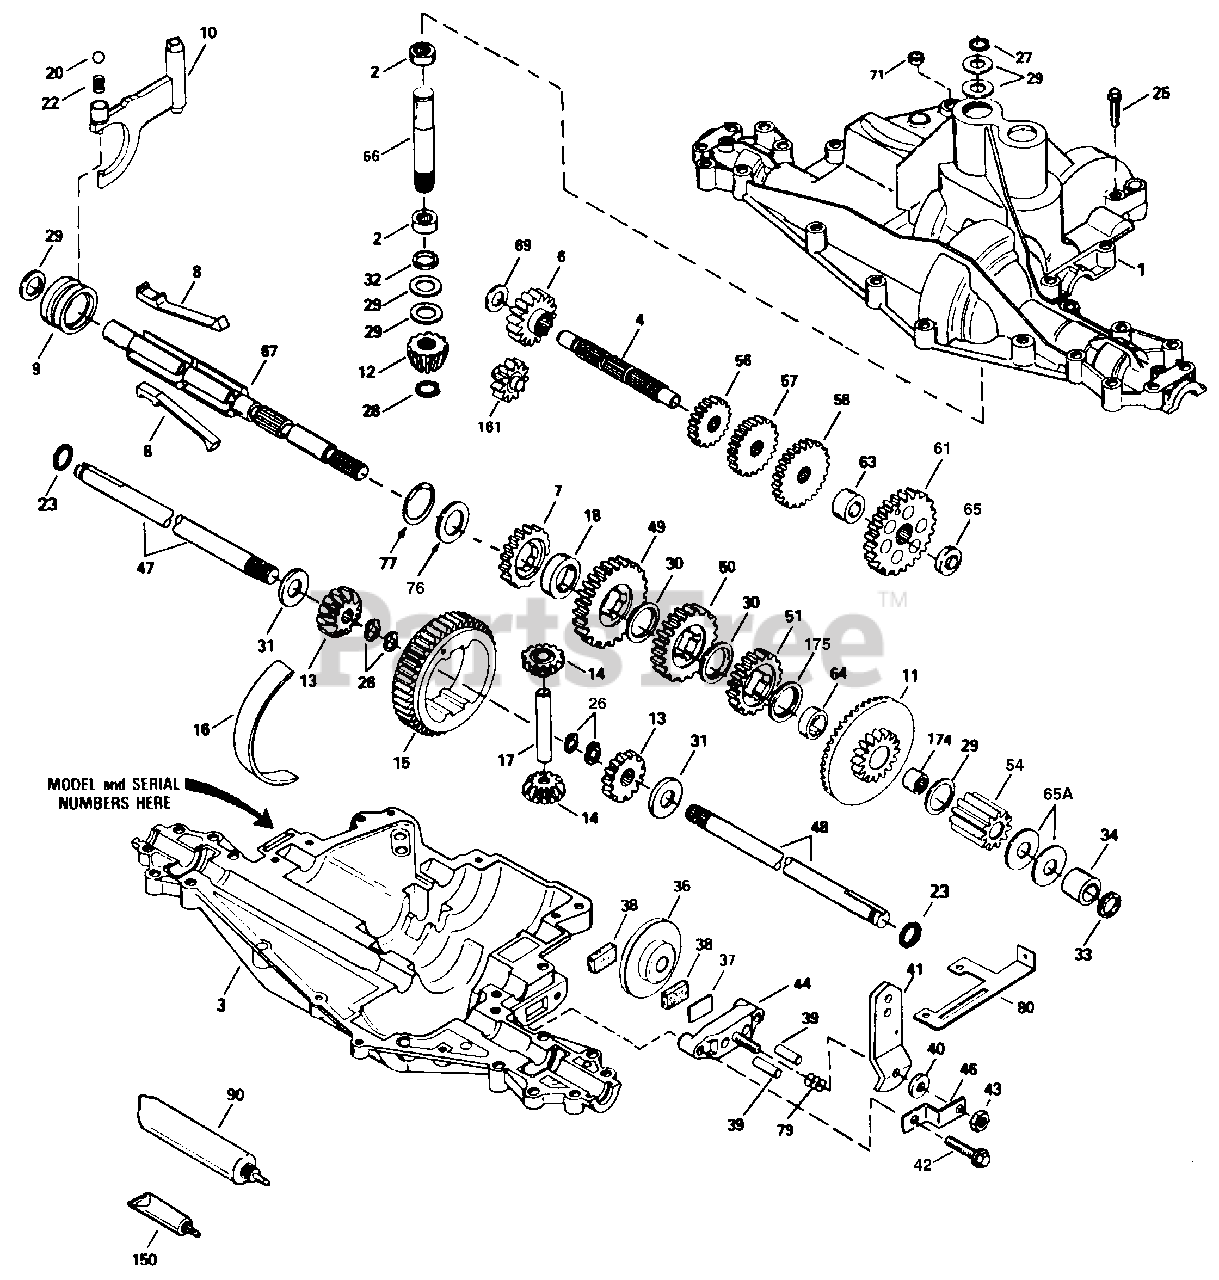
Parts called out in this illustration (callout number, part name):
1	Transaxle Cover
2	Needle Bearing
3	Transaxle Case
4	Countershaft
6	Spur Gear (16 teeth)
7	Spur Gear (22 teeth)
8	Shift Key
9	Shift Collar
10	Shift Rod & Fork
11	Bevel Gear & Bearing
12	Bevel Pinion (14 teeth)
13	Bevel Gear (16 teeth)
14	Differential Pinion
15	Ring Gear
16	Bearing Strip
17	Drive Pin
18	Neutral Spacer
20	Ball, 5/16" dia.
22	Spring
23	Seal Ring
25	Screw, 1/4-20 x 1-1/4"
26	Retaining Ring
27	Retaining Ring
28	Retaining Ring
29	Washer
30	Washer
32	"O" Ring
33	"O" Ring
36	Brake Disk
37	Brake Pad Plate
38	Brake Pad (pkg. of 2)
39	Dowel Pin
41	Brake Lever
42	Screw, 1/4-20 x 1-1/4"
43	Locknut, 5/16-24
44	Brake Pad Holder
46	Brake Lever Bracket
47	Axle (16-1/4" long)
48	Axle (11" long)
49	Spur Gear (25 teeth)
50	Spur Gear (22 teeth)
51	Spur Gear (19 teeth)
54	Spur Gear (11 teeth)
56	Spur Gear (25 teeth)
57	Spur Gear (28 teeth)
58	Spur Gear (30 teeth)
61	Spur Gear (34 teeth)
64	Output Shaft Spacer
66	Input Shaft
67	Shifter & Brake Shaft
71	Square Cut Ring
77	Inverted Retaining Ring (pkg. of 2)
80	Brake Bracket
90	Grease Specification
150	Gasket Eliminator (Loctite #515)
161	Reverse Idler
174	Needle Bearing
